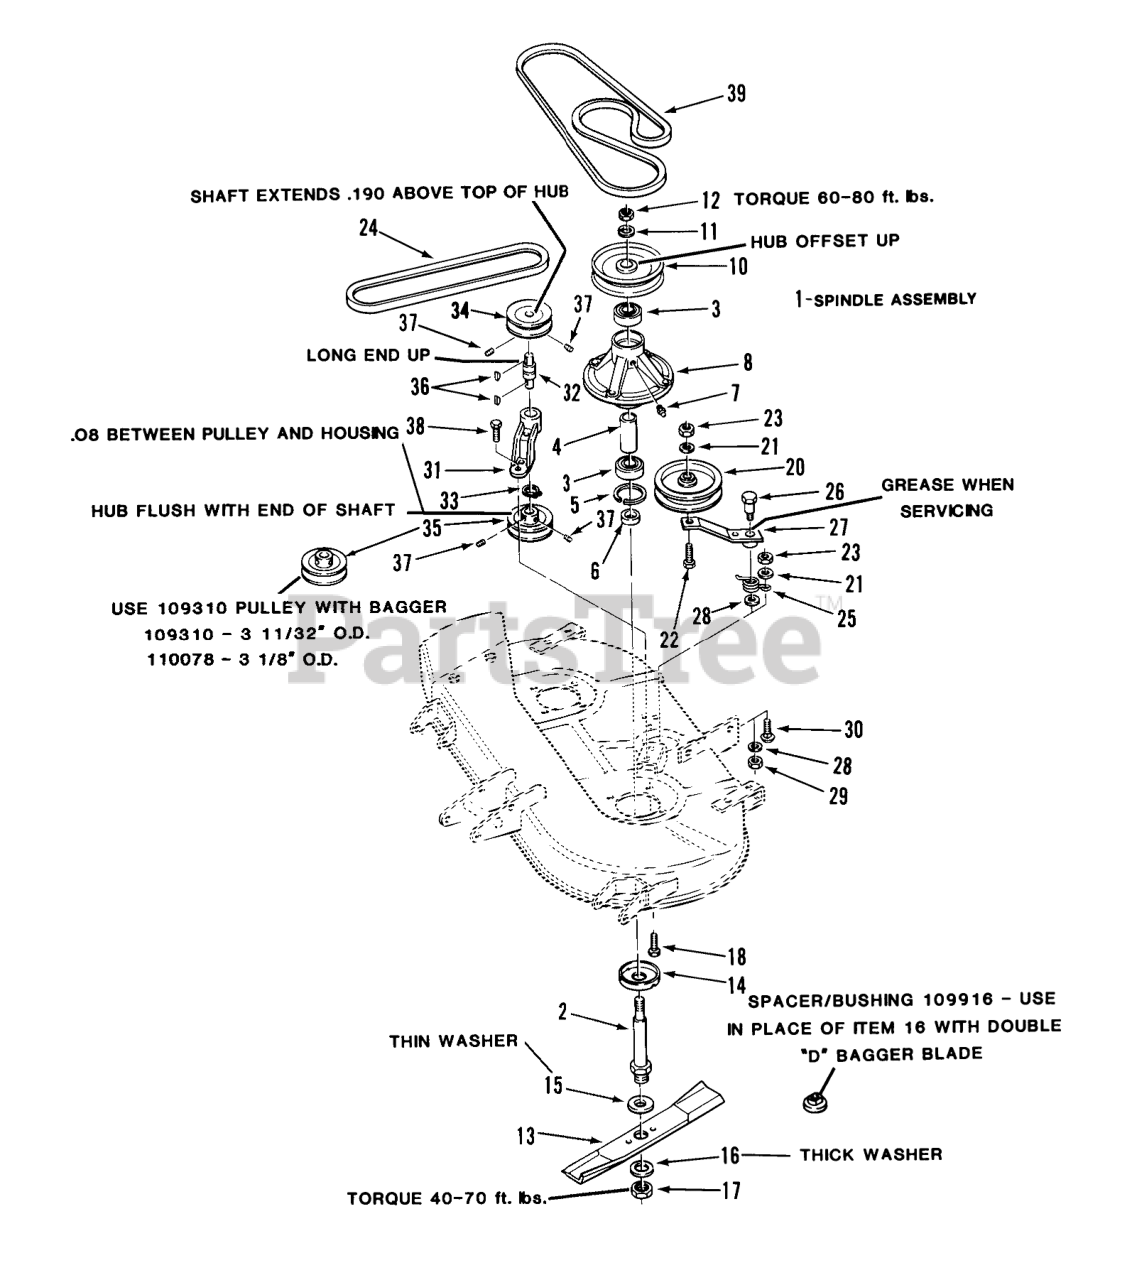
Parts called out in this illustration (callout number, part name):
1	Spindle Assembly, Metric Bearings (includes parts 2 to 8, 14)
2	SHAFT SPINDLE
3	BEARING-BALL
5	Ring-Snap
6	SPACER-BLADE
7	Fitting-Grease
8	HOUSING SPINDLE
10	PULLEY BLADE
11	Lockwasher
12	Jam Nut
13	ASSY BLADE KIT
14	CUP-SPINDLE
15	Washer
16	SpeciaI Washer
17	Nut-Jam
18	Bolt
20	Idler Pulley
21	Washer
22	Bolt
23	Nut
24	V-BELT
25	SPRING-TORSION
26	BOLT-SHOULDER
27	Idler Arm
28	WASHER
29	NUT-JAM(7/16-14)
30	Bolt
31	HOUSING DRIVE BRG R
32	BEARING-INT SHAFT
33	Snap Ring
34	PULLEY
35	PULLEY LOWER
36	KEY-WOODRUFF
37	Set Screw
38	Bolt
39	V-BELT
